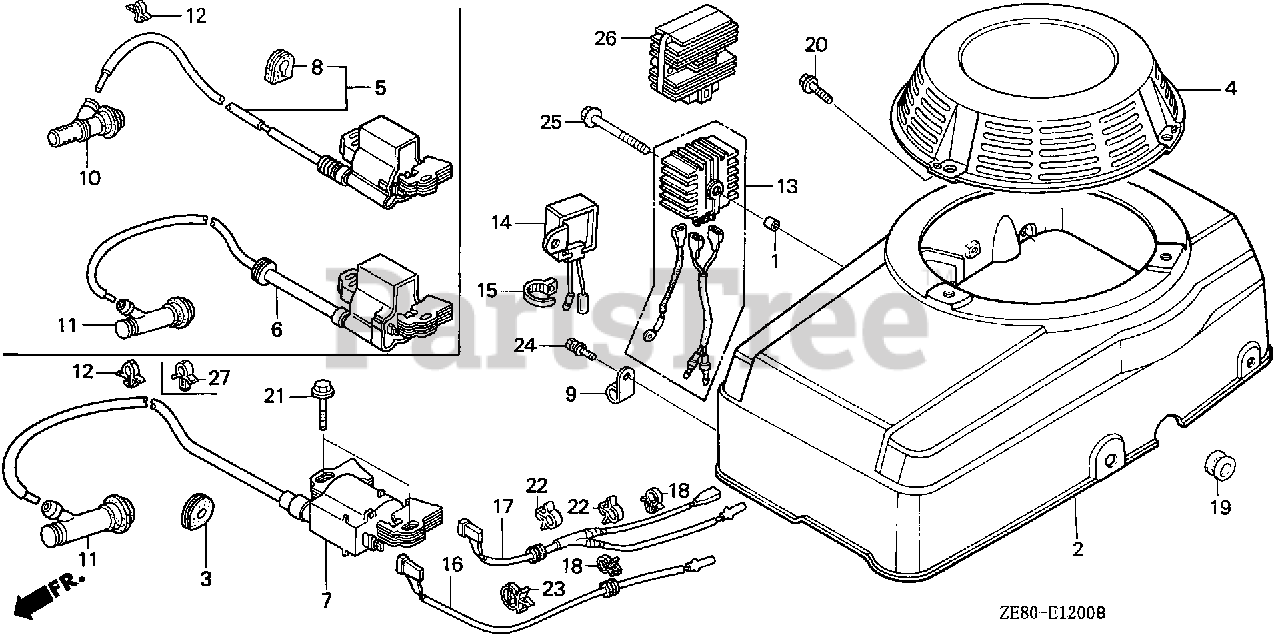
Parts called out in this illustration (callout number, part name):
1	SPACER, AIR CLEANER ELBOW
2	COVER, FAN (NOT AVAILABLE)
5	COIL ASSY., IGNITION (NOT AVAILABLE)
8	GROMMET, IGNITION
9	CLAMP, IGNITION WIRE
10	CAP ASSY., NOISE SUPPRESSOR
13	RECTIFIER ASSY., SILICON
17	WIRE, STOP SWITCH
18	HOLDER, STOP SWITCH WIRE
19	GROMMET, WIRE CORD
20	BOLT, FLANGE (6X12) (CT200)
21	BOLT, FLANGE (6X28) (CT200)
23	CLIP, HARNESS
24	SCREW-WASHER (5X12)
25	BOLT, FLANGE (6X40)
